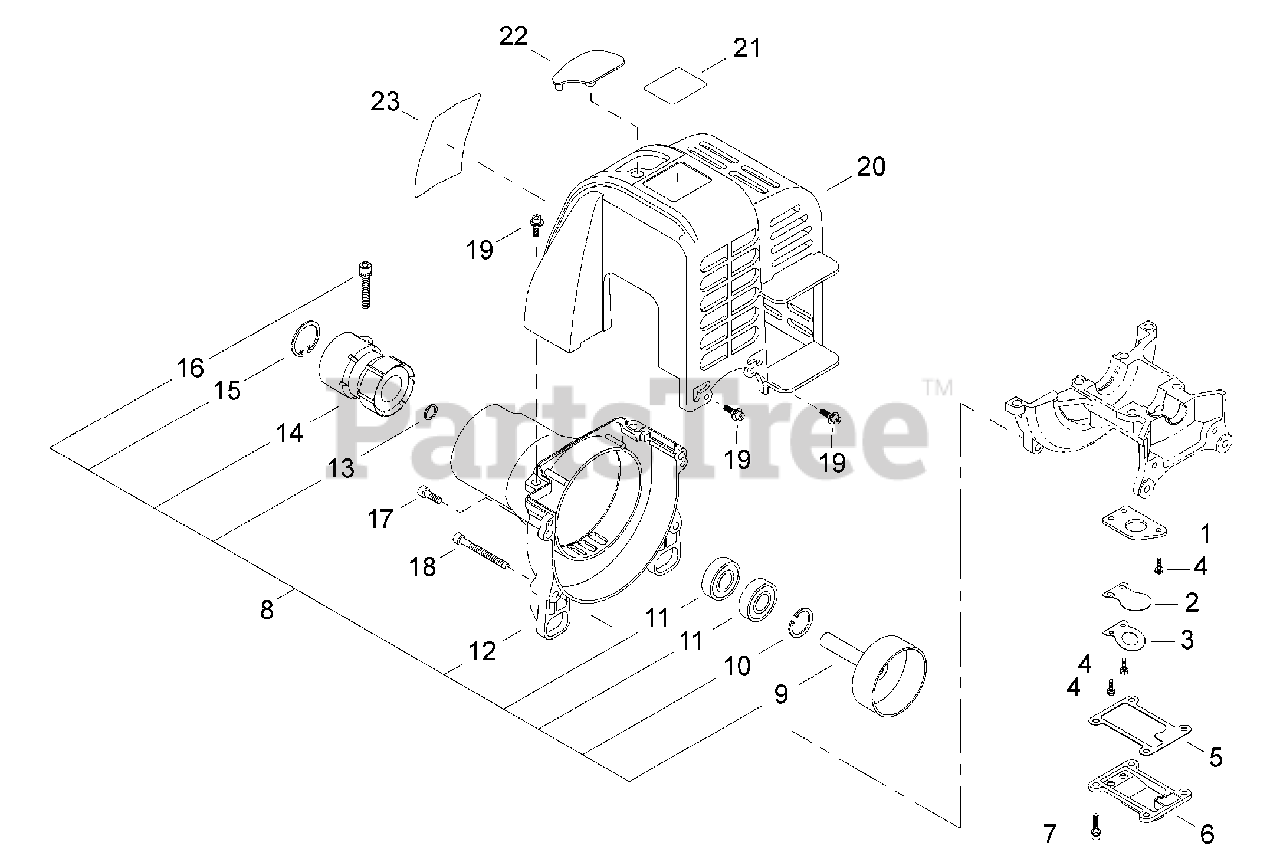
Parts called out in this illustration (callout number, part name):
1	PLATE, REED BACKING
2	VALVE, REED
3	STOP, REED VALVE
4	SCREW M3×10
5	GASKET, REED VALVE
6	COVER, REED VALVE
7	BOLT M4×12
8	COVER ASSY, FAN
9	DRUM, CLUTCH
10	RING, SNAP Ø26
11	BEARING, BALL 6000ZZ
12	COVER, FAN
13	RING, SNAP WR10
14	CUSHION, AV
15	RING, SNAP Ø40
16	BOLT M5×22
17	BOLT 5×16
18	BOLT M5×45
19	BOLT M4×16
20	COVER, ENGINE
21	LABEL, AH2510
22	COVER, SPARK PLUG
23	LABEL, C4 SHINDAIWA
